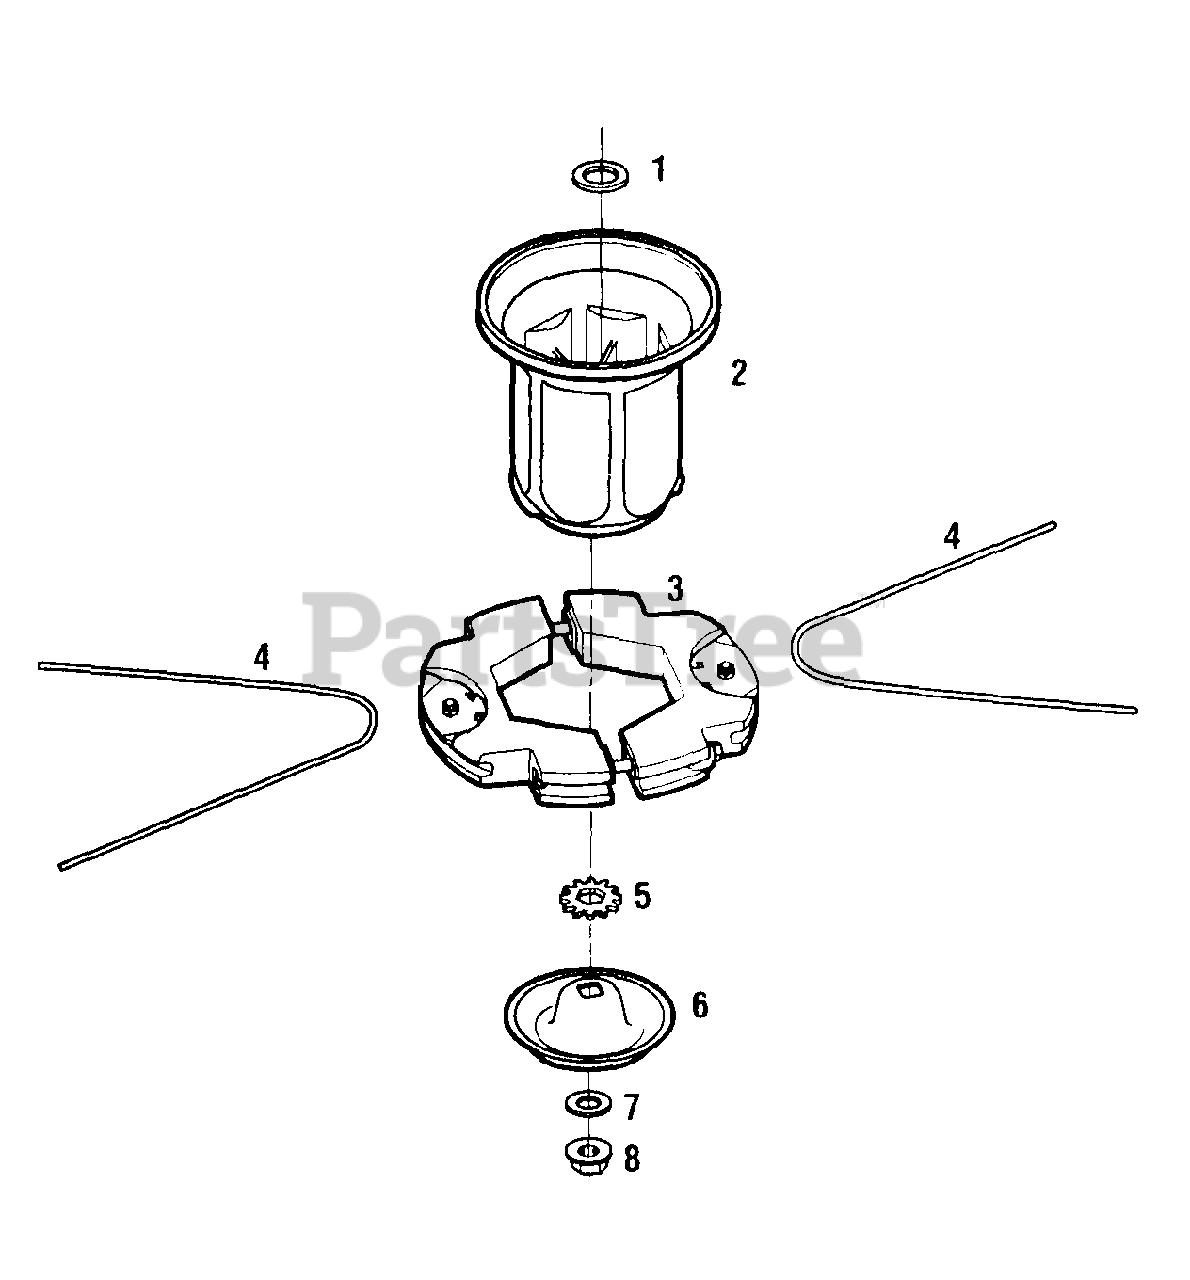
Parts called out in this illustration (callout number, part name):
1	Shoulder Washer
2	Spindle Head
3	Trimmer Head
4	Trimmer String
5	Hex Spline Washer
6	Wear Cup
7	Washer
8	Hex Flange Nut, 1/2-13
